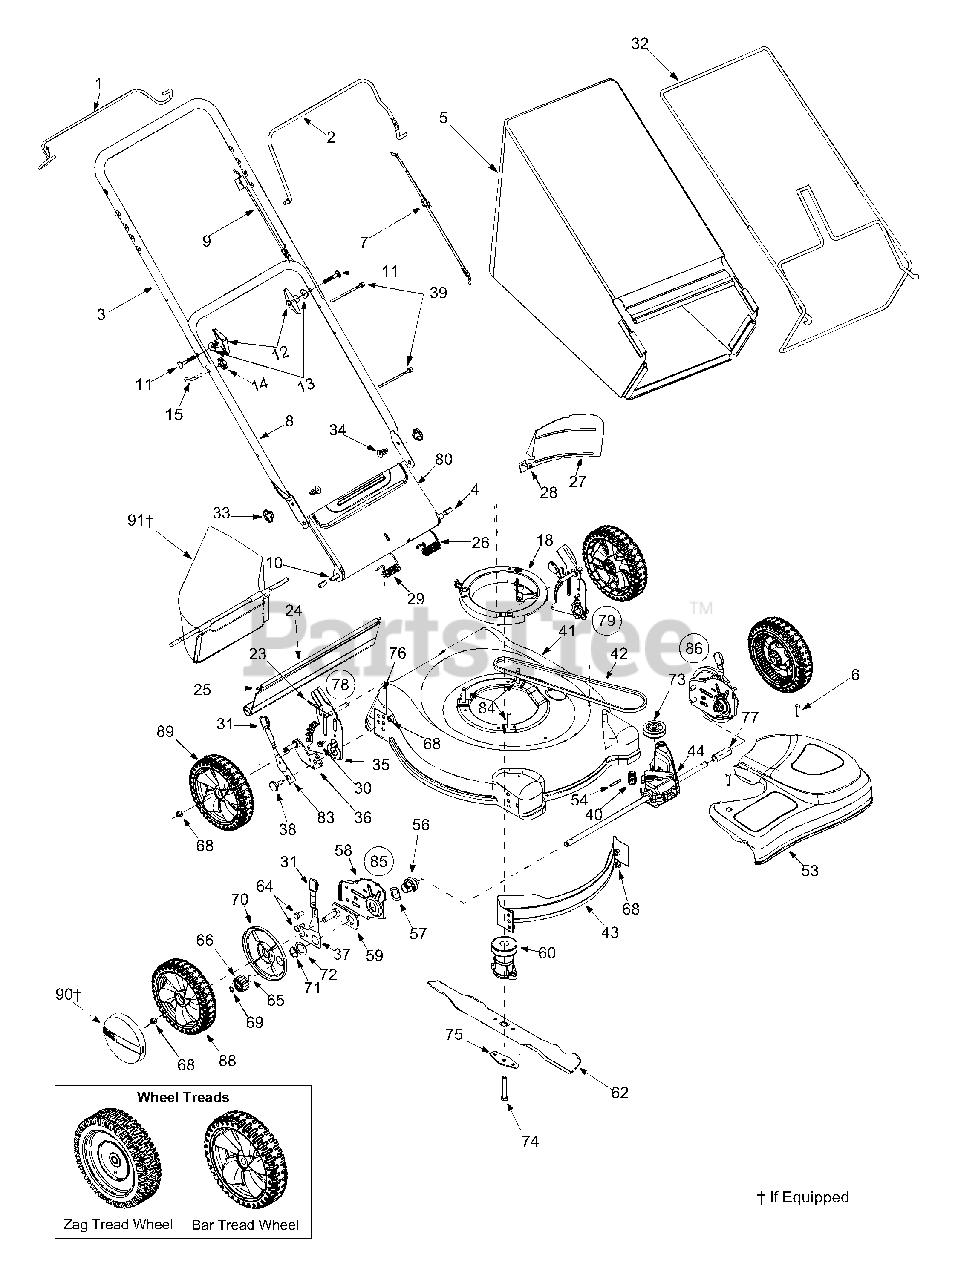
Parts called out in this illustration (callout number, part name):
1	Lower Bail Handle
4	Spacer.390 x.810 x.950"
5	Grass Bag
6	Shoulder Screw
7	Control Cable: 37.75"
9	Drive Cable
10	Rear Door Pivot Rod
11	Carriage Bolt
12	Handle Knob
13	Saddle Washer
14	Wing Nut
15	Rope Guide
18	Engine Spacer Assembly
23	Hairpin Clip
24	Rear Trail Shield
25	Trail Shield Wire
26	Torsion Spring LH
28	Screw 1/4-14 x 0.625"
29	Torsion Spring RH
30	Hex Screw w/ Wash. 1/4-20 x 0.625"
31	Knob
33	Wing Nut
34	Hex Carriage Screw
35	Handle Bracket RH
36	Pivot Arm Assembly RH
37	Front Lever RH
38	Shoulder Screw
39	Cable Tie
40	Belt Tension Spring
41	Rear Discharge Deck, 21"
42	V-Belt
53	Front Drive Cover
54	Roll Pin
56	Bearing Assembly
57	Wave Washer
60	Blade Adapter / Pulley Assembly
62	Mulching Blade w/ Star, 21"
64	Hex Screw
65	Dowel Pin
66	Gear 14T RH
68	Hex Nut, 3/8-16
69	Snap Ring
70	Wheel Dust Cap
71	Snap Ring
72	Washer, 1.5" O.D.
73	Input Pulley
74	Hex Bolt, 3/8-24 x 2.5
75	Bell Blade Support
77	Slev. Spacer LH
78	Handle Bracket Assembly RH
79	Handle Bracket Assembly LH
80	Chute Door
83	Spring Lever
84	Self-tapping Screw, 3/8-16 x 1.875
85	Height Adj. Assembly RH
86	Height Adj. Assembly LH
88	Front Wheel
89	Rear Wheel
90	Hub Cap, Gray (Fits Zag Tread Wheels)
91	Chute Deflector Accessory
